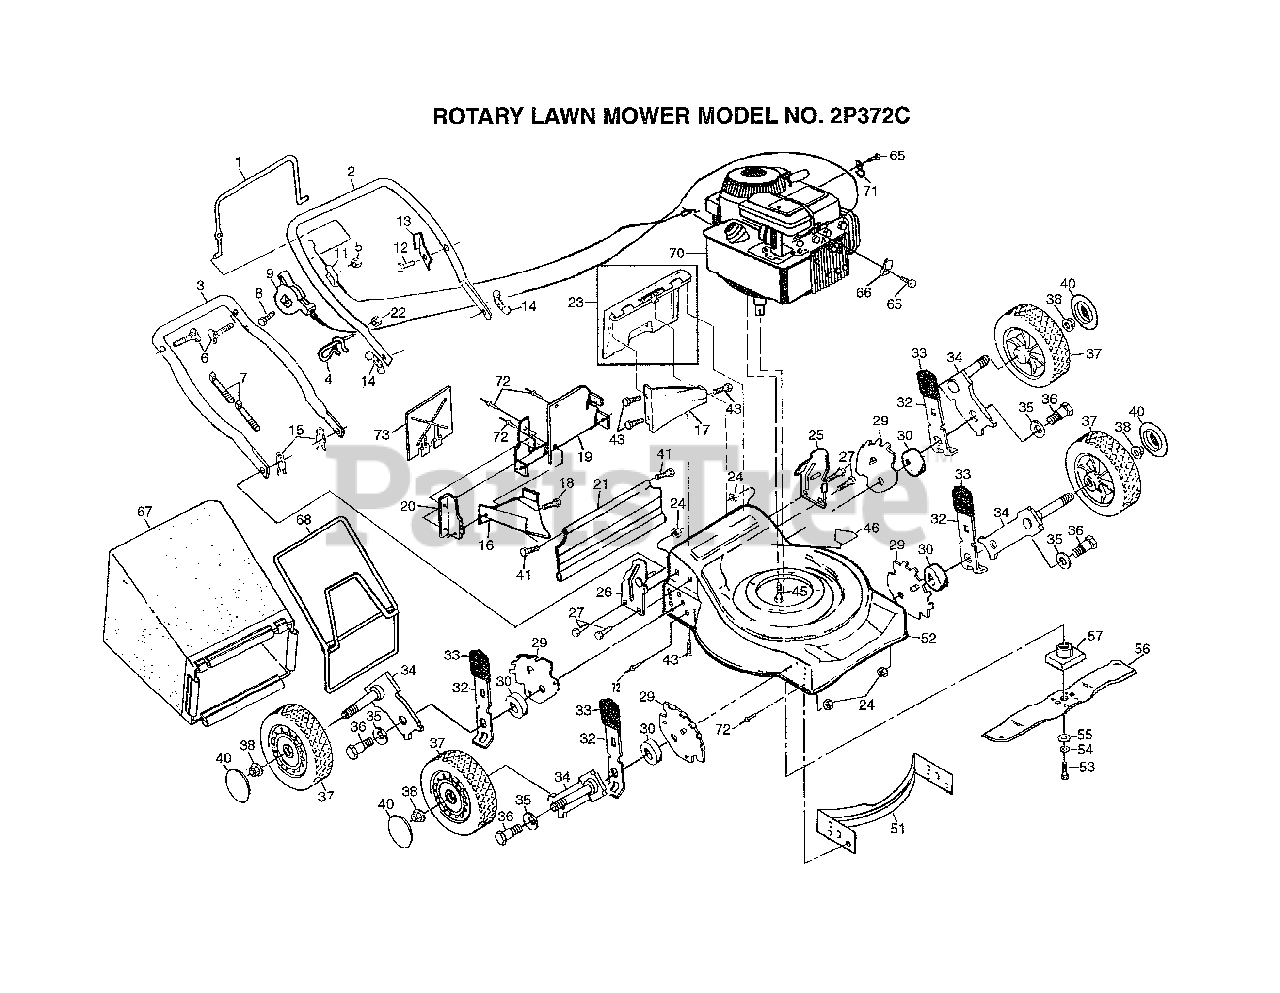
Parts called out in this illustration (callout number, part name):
1	CONTROL BAR
4	ROPE GUIDE
6	BOLT.HANDLE.LM
8	SCREW.HXHD.WASH.
9	CONTROL THROTTLE
11	"CABLE,ENG ZONE CO"
12	TAPPING SCREW
13	"BRKT,UPSTOP"
14	"NUT,WING PM"
15	HAIRPIN COTTER
16	DISCHARGE GUARD
17	REAR BAFFLE
18	SCREW PM
19	PLATE.BACK.20RD
21	SKIRT.PUSH.20RD
22	NUT
23	KIT.DOOR.RR.20STL
24	LOCKNUT PM
27	SCREW
29	BRACKET.ADJ.9POS.
32	SPRING SELECTOR
33	KNOB PM
34	ARM.AXLE.ASM.BZP.
35	"WASHER, BELLEVIL."
36	BOLT SHLD 3/8-16
37	WHEEL.8X1.75.WHT
38	HEX FLANGE LOCKNT
40	HUB CAP
41	HINGE SCREW
43	SCREW
45	SCREW
46	DECAL HYT
53	SCREW
54	LOCKWASHER
55	"WASHER,HARDEN"
56	BLADE.20.MULCH.AY
57	BLADE ADAPTOR
65	SCREW PM
66	CABLE CLAMP
67	GRASSBAG.250B1.BL
68	FRAME.CATCHER.2.5
71	GUIDE CLIP PM
72	BLIND RIVET
73	MULCHER PLATE
